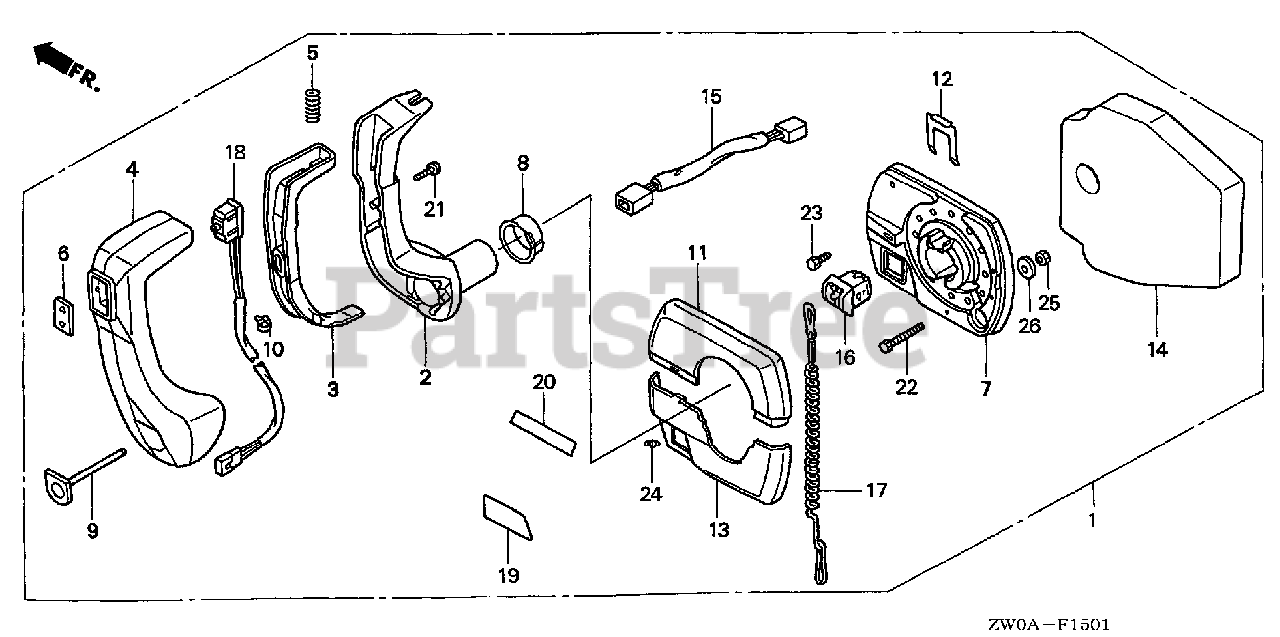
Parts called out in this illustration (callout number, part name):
1	BOX ASSY., REMOTE CONTROL
2	HANDLE, REMOTE CONTROL
3	LEVER, HANDLE LOCK
4	GRIP, REMOTE CONTROL HANDLE
5	SPRING, REMOTE CONTROL HANDLE
6	COVER, GRIP
7	HOUSING ASSY., REMOTE CONTROL
9	BUTTON, THROTTLE
10	BAND B, CABLE
11	HOUSING, REMOTE CONTROL BOX
13	HOUSING, REMOTE CONTROL BOX
14	HOUSING ASSY. (INNER)
15	HARNESS ASSY., POWER TRIM-TILT
16	SWITCH ASSY., EMERGENCY STOP
17	WIRE, EMERGENCY
18	SWITCH ASSY., POWER TRIM-TILT
19	MARK, REMOTE CONTROL
20	MARK, REMOTE CONTROL
24	SCREW SET (1/4-20X16")
25	NUT (1/4X20)
